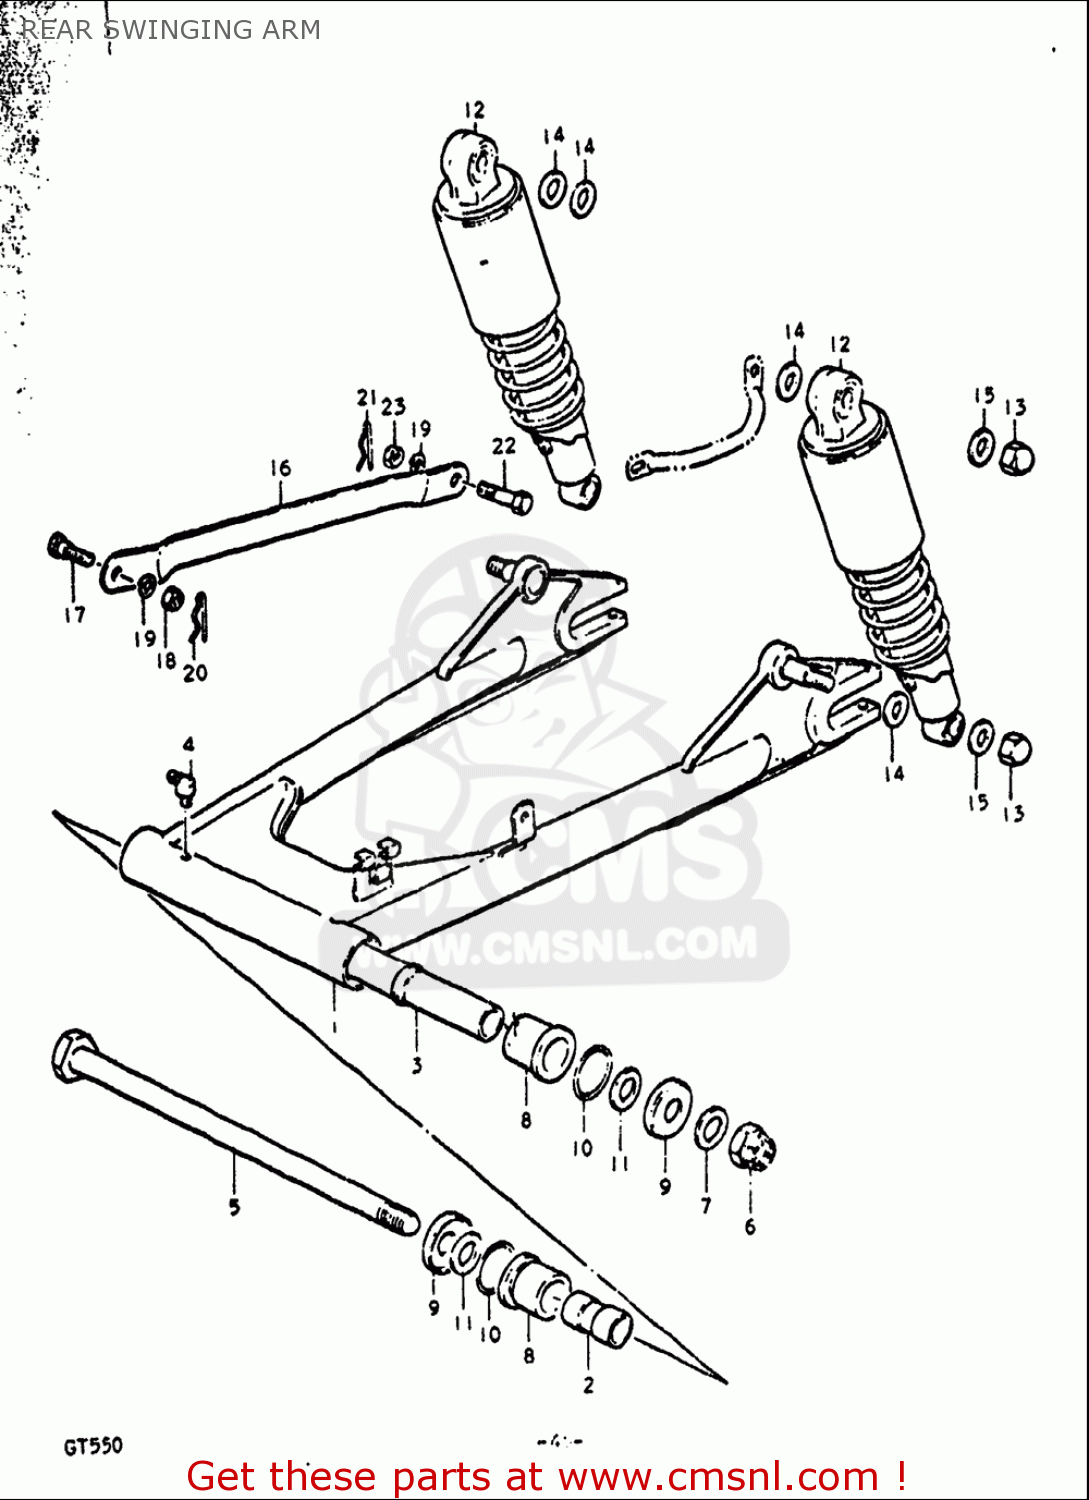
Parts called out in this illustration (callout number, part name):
2	BUSH
4	NIPPLE,GREASE
5	SHAFT,REAR SWING ARM
7	WASHER
8	SPACER
9	COVER
10	O RING(D:3,ID:29.5)
11	WASHER(14.5X29X2.3)
13	NUT
14	WASHER
15	WASHER (10.5X24X2.3)
18	WASHER,LOCK
19	WASHER,LOCK
20	SPRING,RETAINER
21	CLIP
23	NUT
